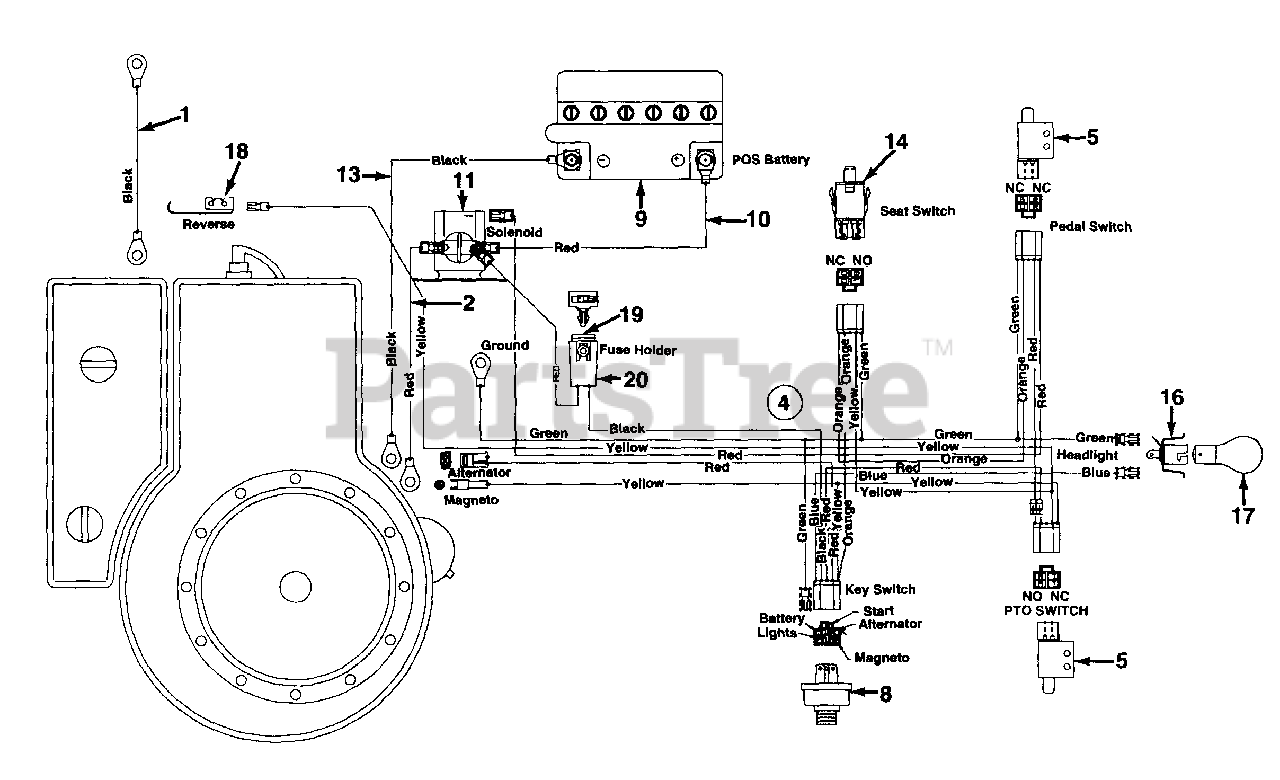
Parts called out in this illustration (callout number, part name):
1	Elec. Wire 8 Ga. x 11.5" Lg. (Black)
2	Elec. Wire 8 Ga. x 15.5" Lg. (Red)
4	Wire Harness
5	Safety Switch
8	Ignition Switch
9	Battery 12V
10	Elec. Wire 8 Ga. x 22" Lg. (Red w/Boot)
11	Solenoid
13	Elec. Wire 8 Ga. x 17" Lg. (Black)
14	Seat Switch
16	Headlight Socket
17	Lamp
18	Safety Switch
19	Fuse, Automotive Type 7-1/2 Amp.
20	Fuse Holder
